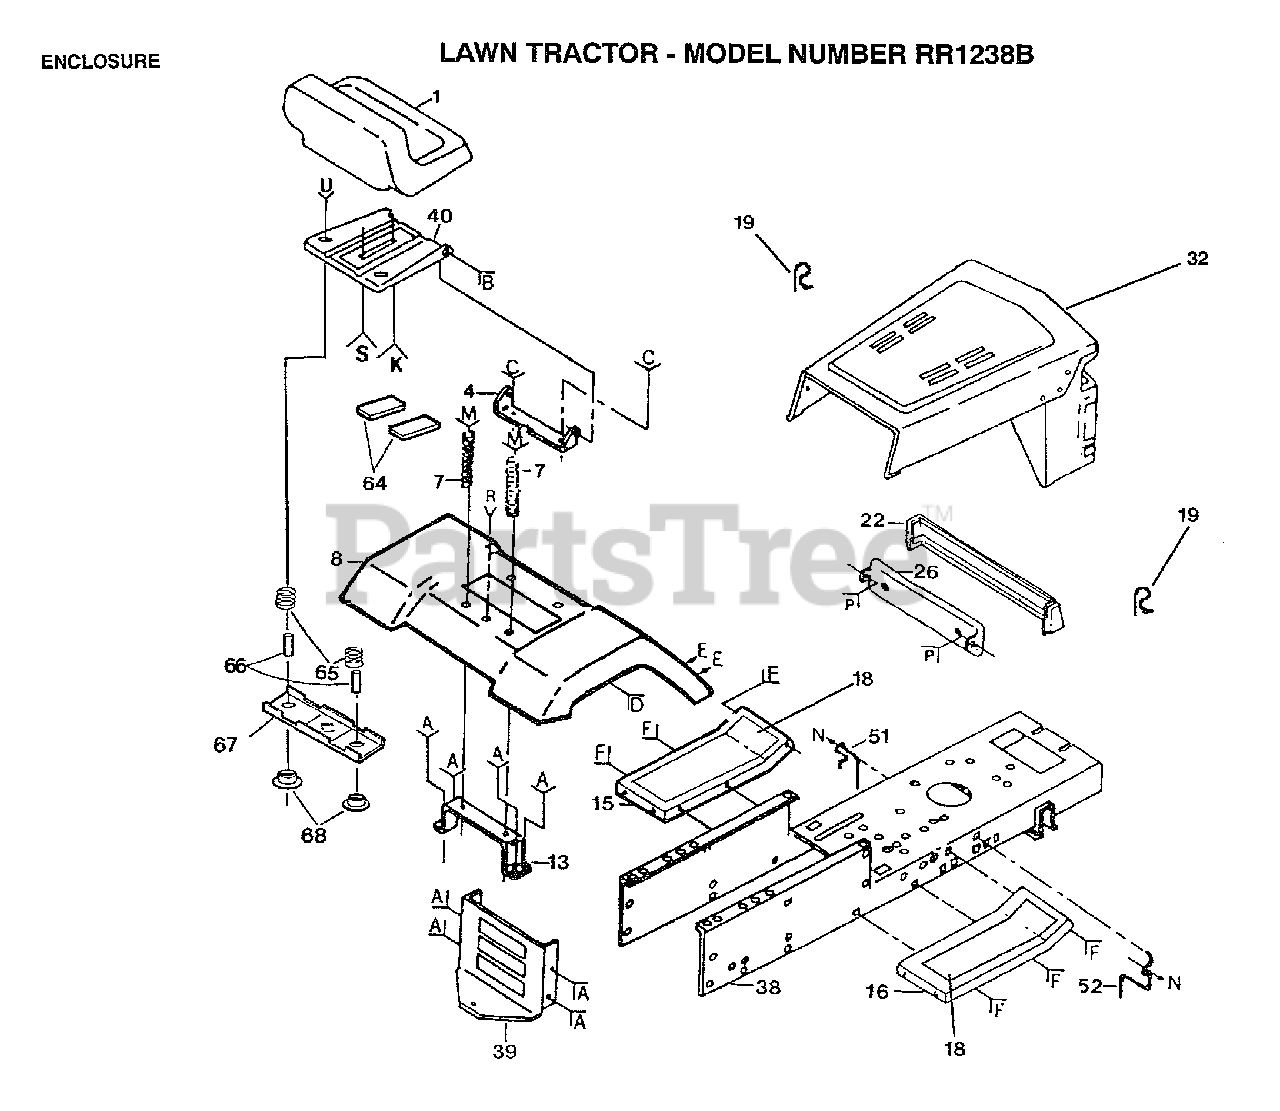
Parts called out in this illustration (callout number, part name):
7	SPRING COMPRESSIO
18	PAD FOOTREST T
19	SPRING.RETAINER
38	CHASSIS ASS'Y
51	BELT GUIDE
52	BELT GUIDE
64	STRIP FORM
65	SPRING
66	SPACER SPLIT
67	BRKT SWITCH
68	BUSHING
